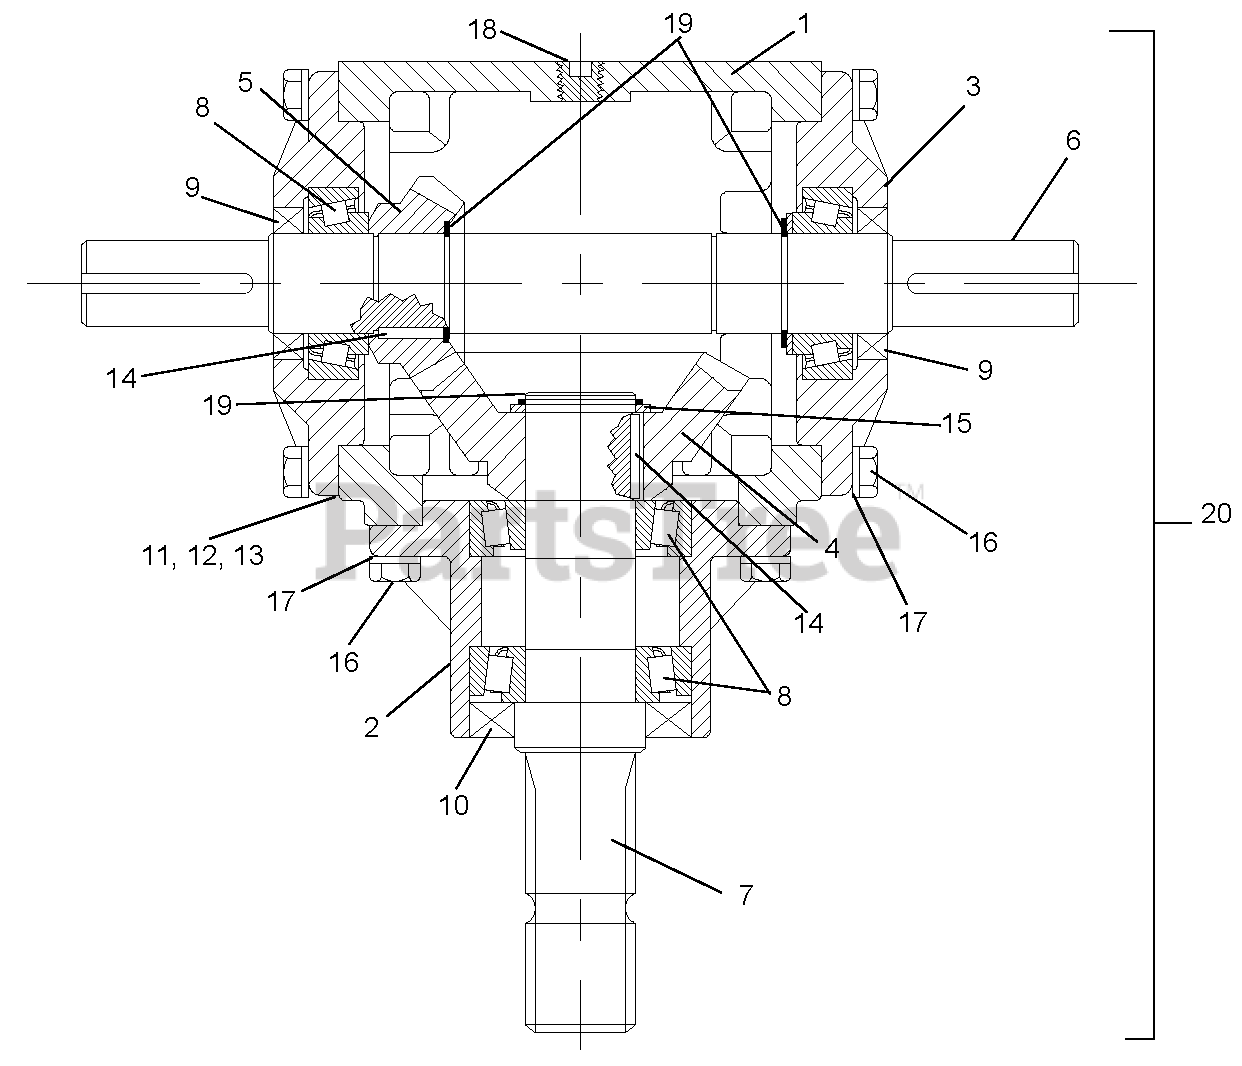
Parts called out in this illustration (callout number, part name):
1	Housing, 400 Series
2	Cap, Cantilevered
3	Cap, Through
4	Gear, 24-Tooth
5	Pinion, 16-Tooth
6	Shaft, Output 1.125W, .25
7	Shaft, Input 1.375-Inch, 6 Spline
9	Seal, Through-Cap Triple Lip
10	Seal, Cantilevered Cap, Triple Lip
11	Gasket, Cap 0.1
12	GASKET CAP 0.2 50022488
13	Gasket, Cap 0.3
14	Key, Square 10mm x 5mm x 25mm
16	Cap Screw, Hex Head .312-18 x 1
17	Washer, Lock .312
18	Plug, Socket Head Pipe .50
19	Ring, Retaining
20	Gearbox Assembly 1:1.5
